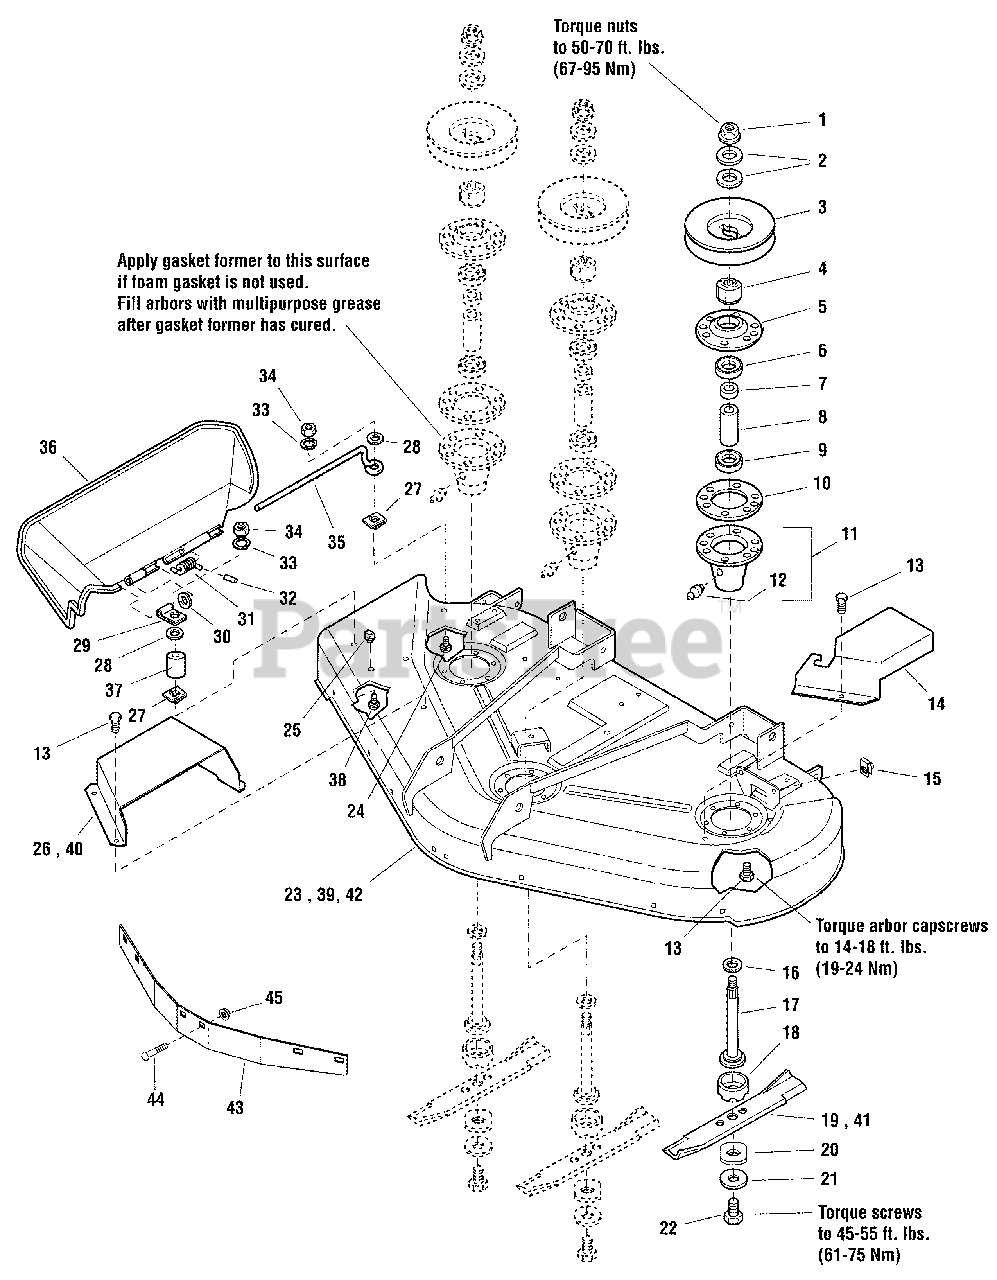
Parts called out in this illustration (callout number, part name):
1	NUT, HEX FLANGE, 9/16-18
2	WASHER, Bellville, 9/16
3	PULLEY
4	HUB
5	COVER, ARBOR HOUSING
6	BEARING, BALL, 3/4 X 1-3/4 X 5/8
7	SPACER, 21/32 X 3/4 X 5/8
8	SPACER, 11/16 X 5/32 X 2-11/16
9	BEARING, BALL, 11/16 X 1-9/16 X 15/32
10	SEAL, FOAM
11	ARBOR HOUSING ASSEMBLY
12	FITTING, GREASE
13	SCREW, HEX WSHR HD TAP TT 5/16-18 X 0.750 BLK
14	GUARD, BELT - LH
15	BODY CLIP, 5/16-18 X 1/2 DEEP
16	WASHER, 9/16, BLACK
17	SHAFT, ARBOR
18	SHIELD, GRASS, LOWER
19	BLADE, MOWER 16.12 .196 THK 44" BM, CONQ
20	WASHER, HEX, 11/16 X 2
21	WASHER, SPRING, 15/32, BLACK
22	BOLT, 7/16-14 X 1-1/4
23	DECK SHELL W/ DECALS, 44 - SNP (2008)
24	BOLT, RD HD SH SQ NK 1/4-20X0. 875 G5 BLK
25	PLUG, BUTTON FOR 0.344 SQ HOLE BLACK POLY
26	GUARD, BELT - RH, 44", SNAPPER RED
27	NUT, PUSH FOR .250 DIA THREAD .500 OD BLK
28	WASHER, 0.250 (0.26 ID X 0.84 OD X .12 THK) BLK
29	CLAMP, WIRE, .312DIA . (1) .281 HOLE BLK
30	WASHER, 0.312 (0.34 ID X 0.75 OD X .06THK) BLK
31	SPRING, TORSION CHUTE 44/50" BLK
32	CAP, VINYL
33	LOCKWASHER, SPRING .250 BLK
34	NUT, HEX 1/4-20 BLK 588514
35	ROD, DEFLECTOR
36	DEFLECTOR, BLACK
37	SPACER, 0.328 ID X 0.499 OD X 0.625 LG PM
38	BOLT, CARRIAGE, 1/4-20 X 1.25, GD5, BLACK
39	DECK SHELL W/ DECALS, 50 - SNP (2008)
40	GUARD, BELT, RH
41	BLADE, MOWER, 18-1/8
42	EXPORT DECK SHELL W/DECALS, 50 - SNP (2008)
43	BAFFLE, FRONT 44/50 - BLACK
44	BOLT, 5/16-18 X 3/4 CARRIAGE
45	NUT, 5/16-18 HEX NYLOCK FLANGE
